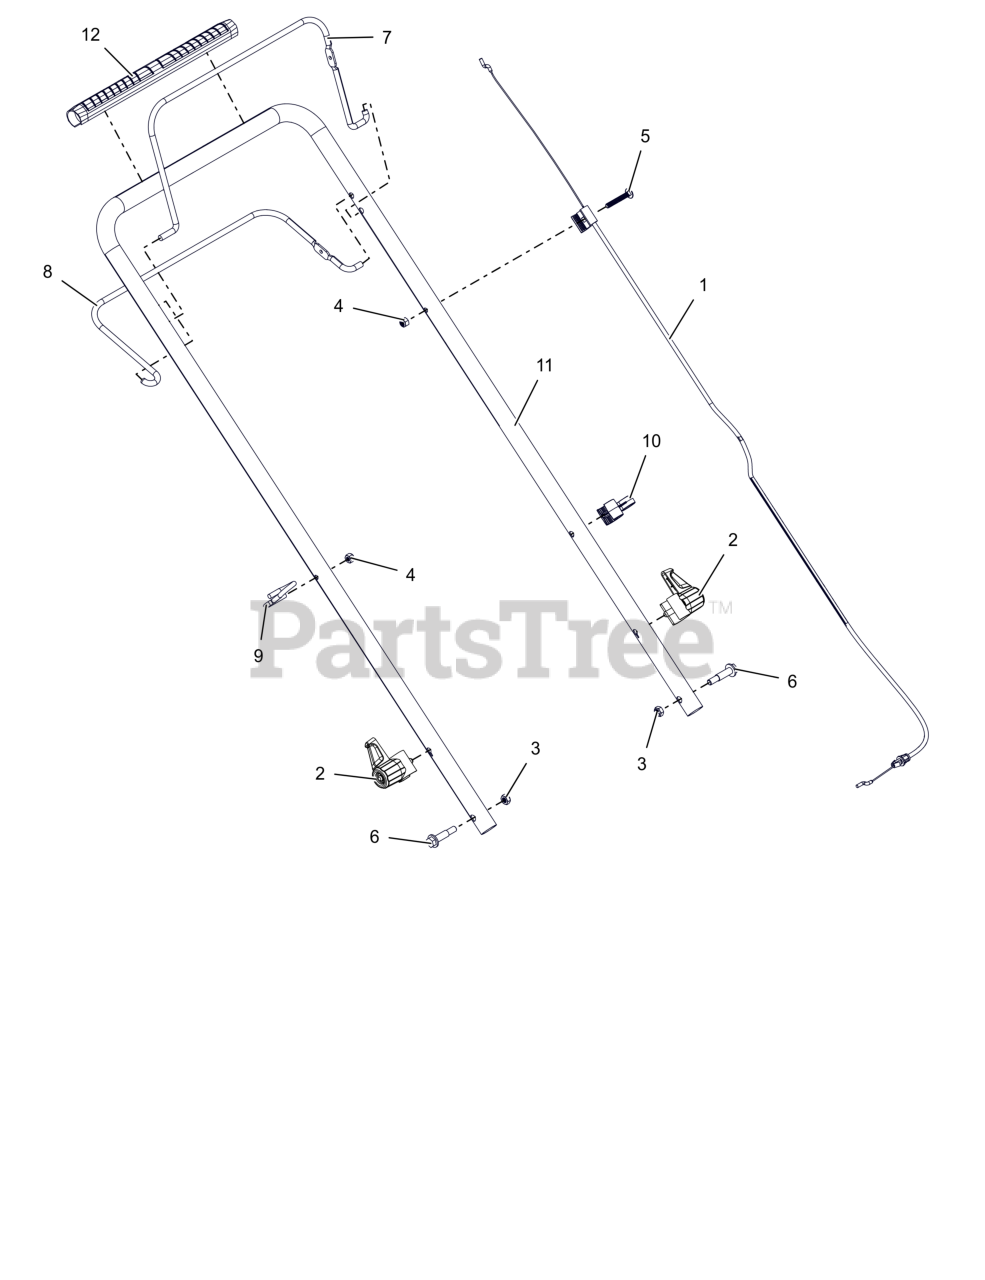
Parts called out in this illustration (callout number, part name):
1	CABLE, FWD OPC
2	ASM, HANDLE ADJUSTER
3	NUT, NYLOC 5/16-18
4	NUT, NYLOC 1/4-20
5	BOLT, CARRIAGE 1/4-20X1.75
6	BLT, SHLDR HWH .65X1.015X 5/16-18
7	BAIL, OPC -SP (GRAY)
8	BAIL, FWD - SP (GRAY)
9	GUIDE, STARTER ROPE (BLACK)
10	GUIDE, CABLE
11	HANDLEBAR, SELF PROPELLED (BLACK)
12	COVER, HANDLEBAR - COMFORT GRIP
